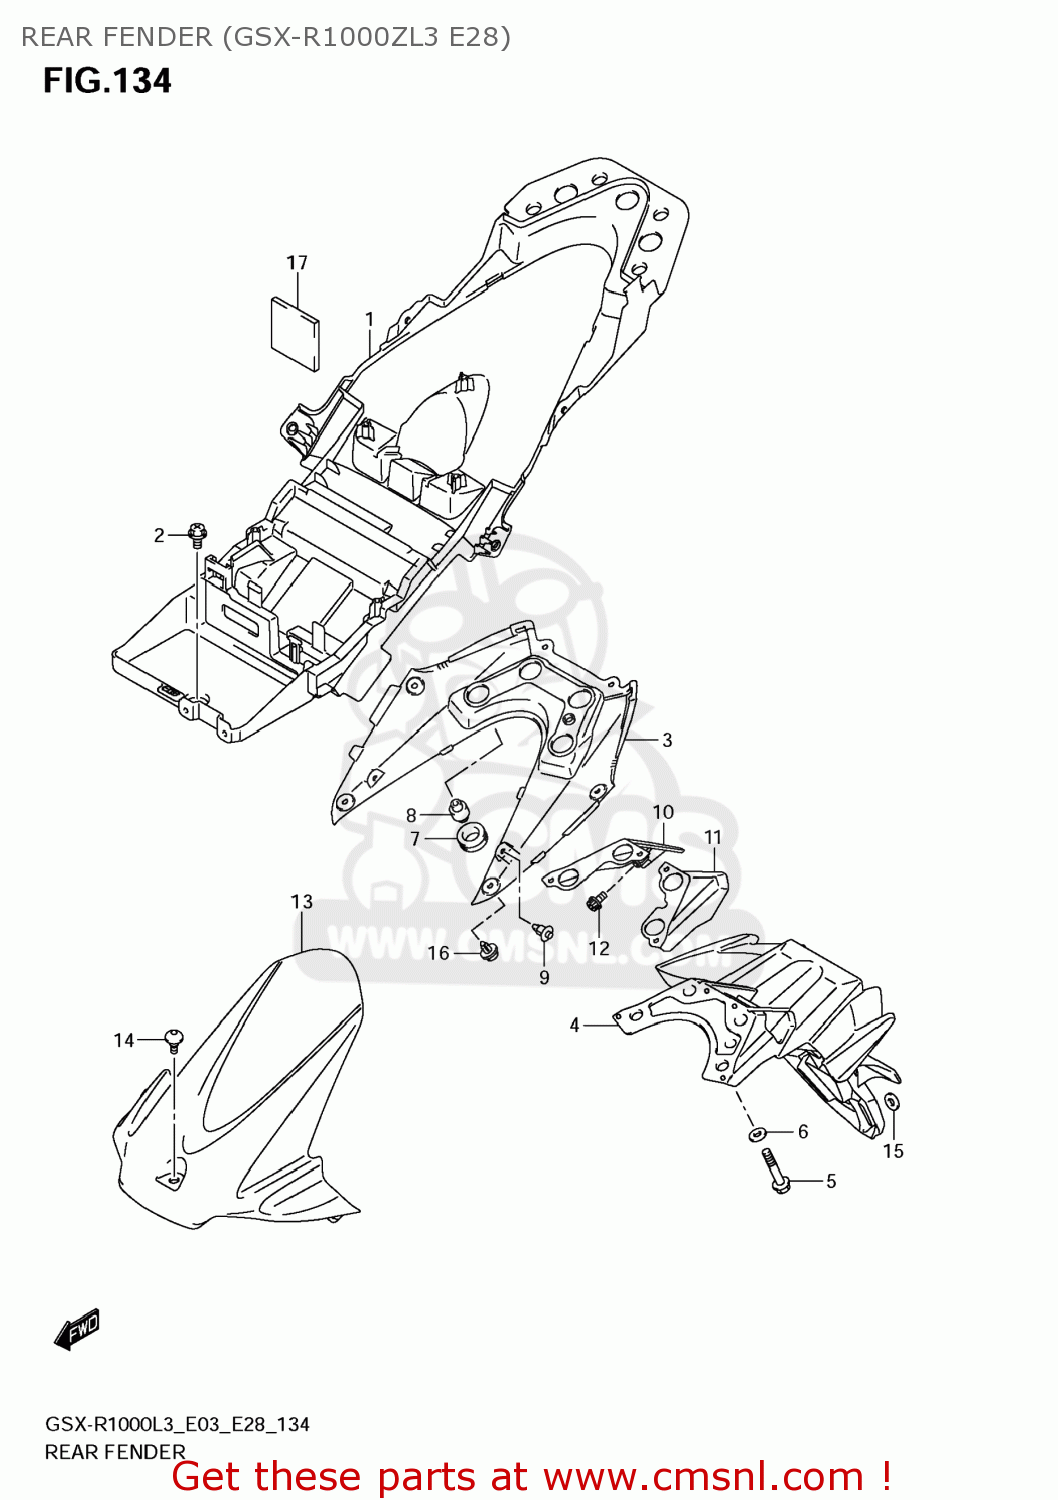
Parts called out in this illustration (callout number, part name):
1	FENDER,RR FR
2	BOLT(6X12)
3	COVER,RR FENDER FR
4	FENDER,RR RR
5	BOLT(6X30)
6	WASHER(6.5X18X1)
7	CUSHION
8	SPACER,RR FENDER RR
9	CLIP(BLACK)
10	COVER,RR FENDER RR,R
11	COVER,RR FENDER RR,L
12	BOLT
13	FENDER,RR LWR
14	SCREW(6X16)
15	WASHER
16	CLIP
17	PROTECTOR(50X50X5)
